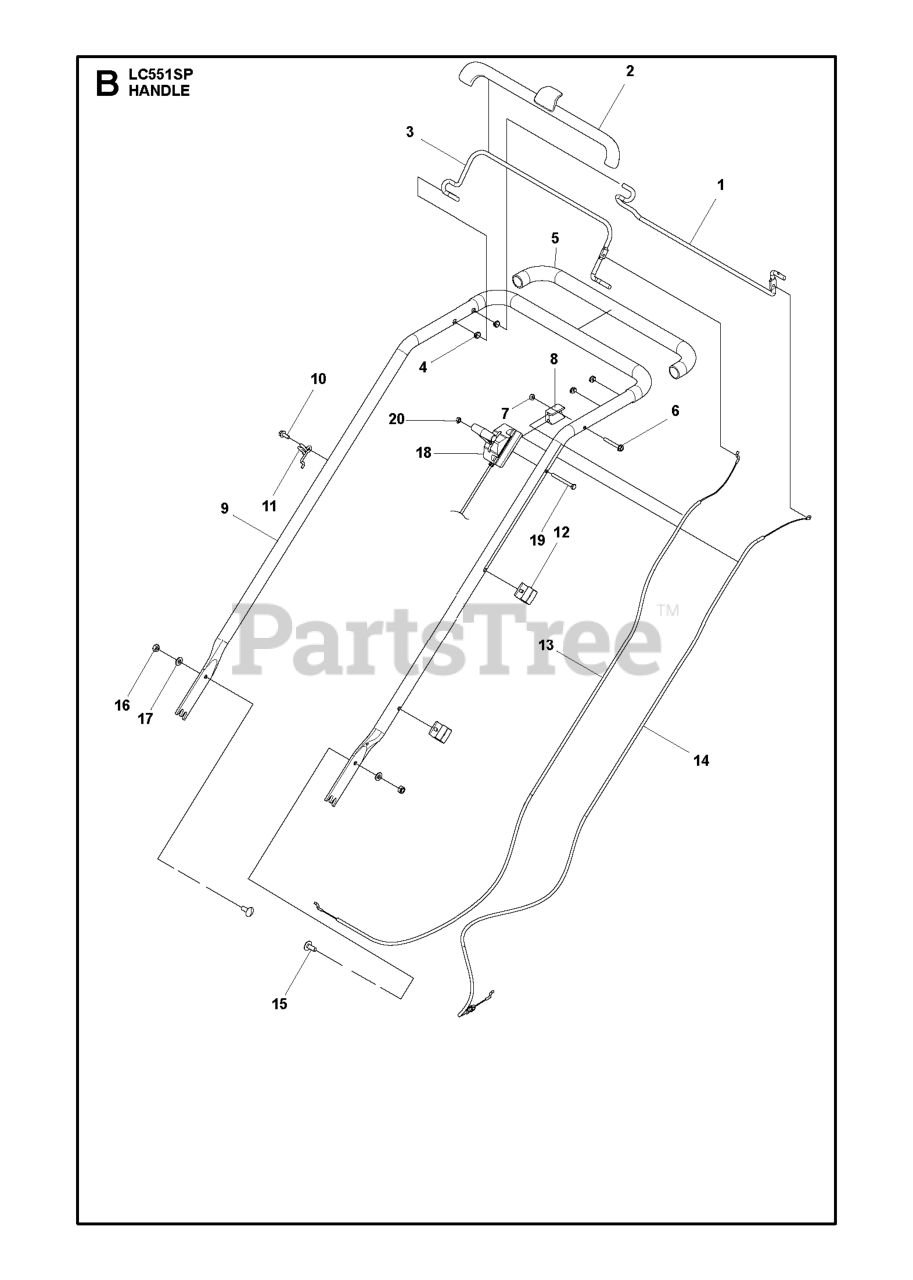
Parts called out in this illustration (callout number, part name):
7	NUT FLANGE - M6
10	SCREW
16	LOCKNUT M8
17	WASHER BRB 8.4X17
20	NUT FLANGE - M6
